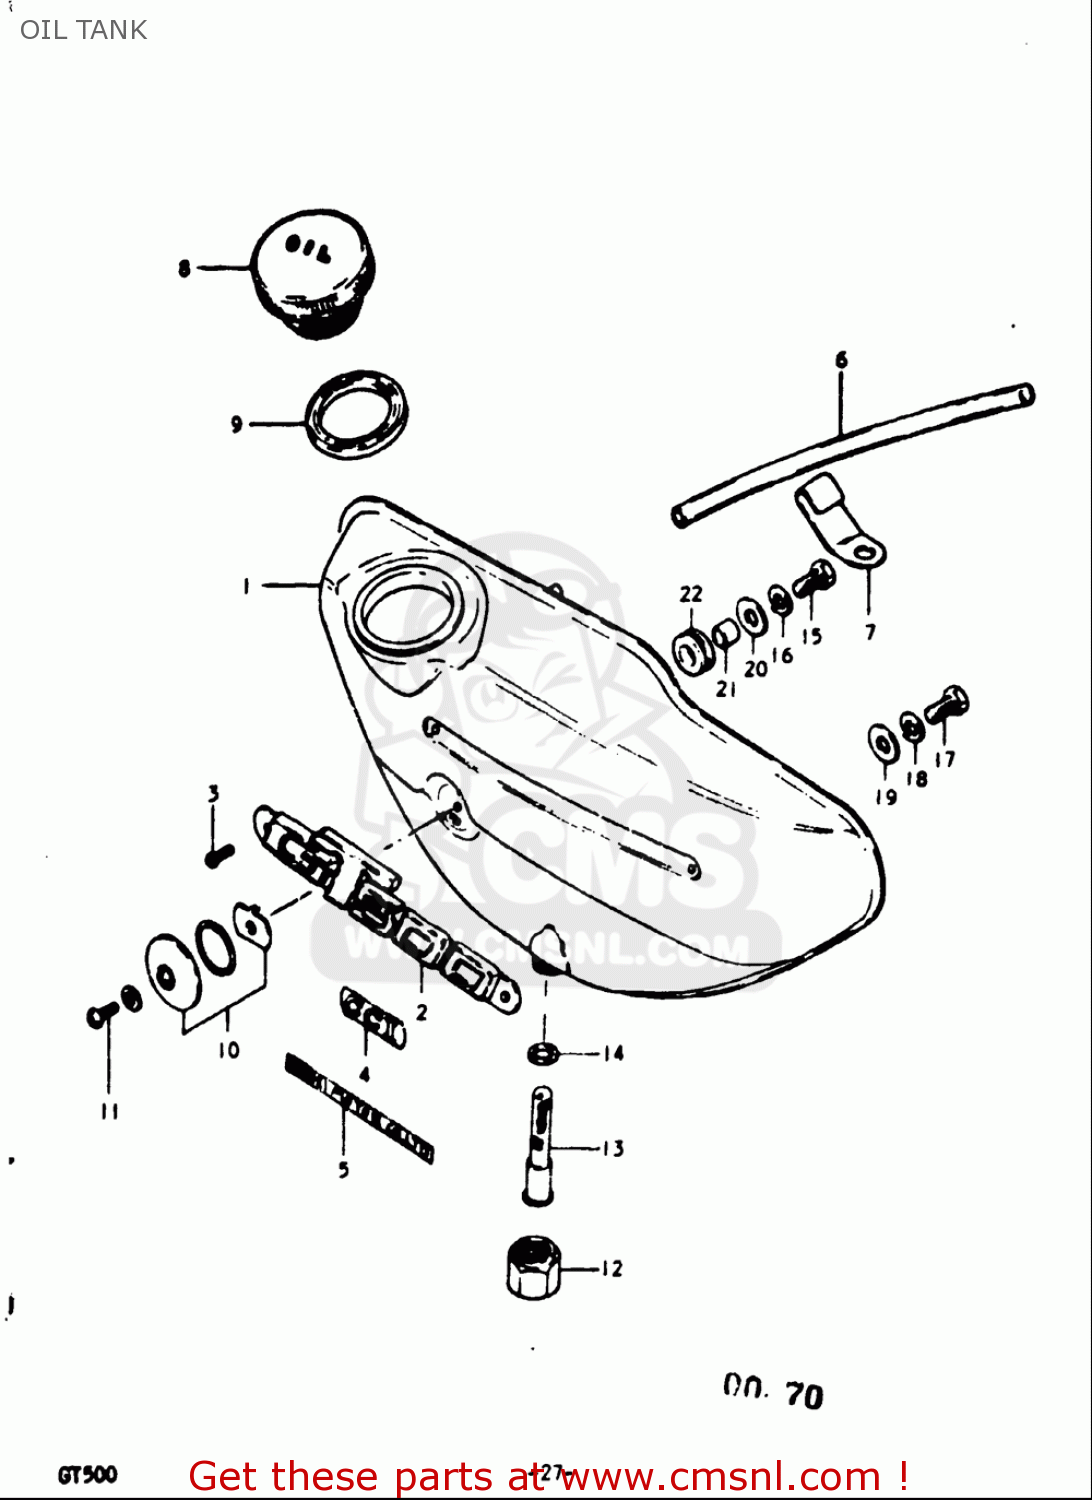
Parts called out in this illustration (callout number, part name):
4	EMBLEM,CCIS
6	HOSE(5X8X2000)
8	CAP,OIL TANK
9	GASKET,OIL TANK FILLER CAP (NAS)
10	LENS SET,OIL INSPECTION
11	SCREW
12	OIL OUTLET JOINT NUT
13	UNIT,OIL FILTER
14	GASKET,OIL OUTLET JOINT (NAS)
15	BOLT
16	WASHER,LOCK
17	BOLT
18	WASHER,LOCK
19	WASHER
20	WASHER(6.5X20X1.2)
21	SPACER(6.1X9X7.5)
22	CUSHION
